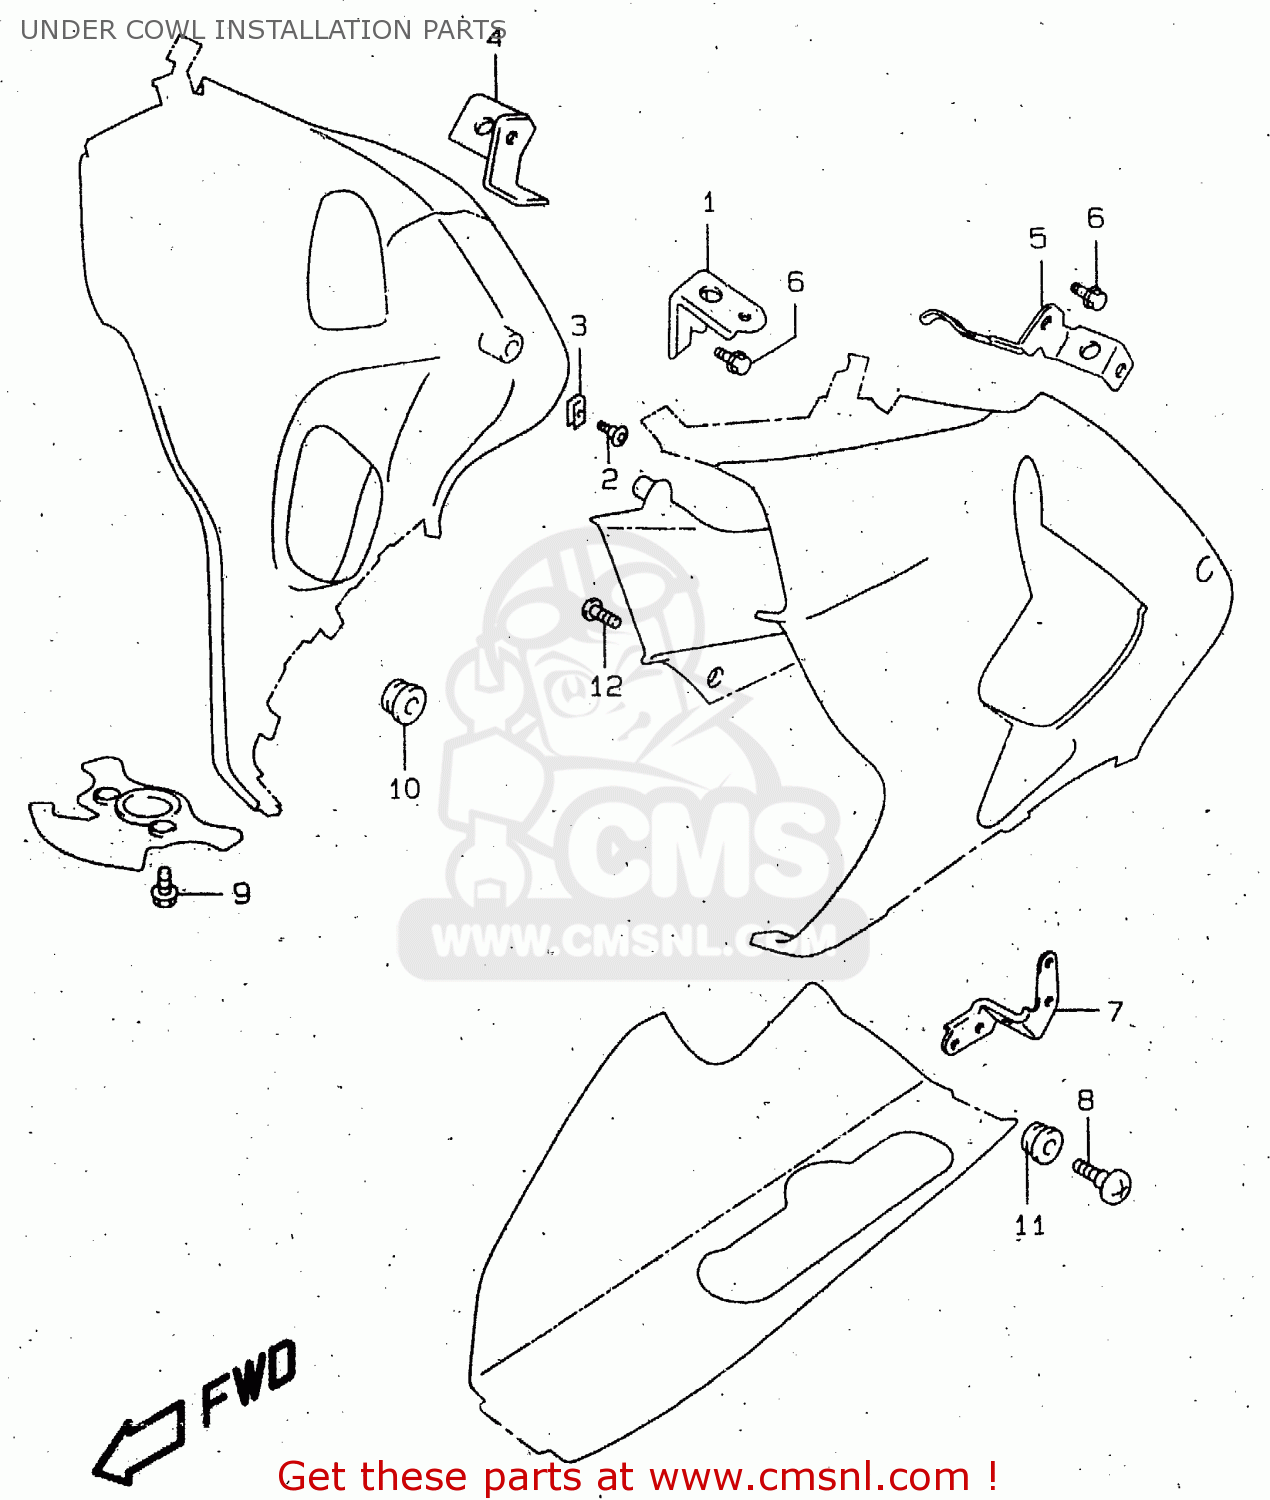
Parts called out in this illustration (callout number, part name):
1	BRACKET,UNDER COWLING UPR
2	SCREW(5X16)
3	NUT,HEADLAMP HOUSING,UPPER
4	BRACKET,UNDER COWLING SIDE,R
5	BRACKET,UNDER COWLING,SIDE
6	BOLT
7	BRACKET,UNDER COWLING,LOWER
8	SCREW(6X20)
9	BOLT
10	CUSHION
11	CUSHION
12	SCREW
